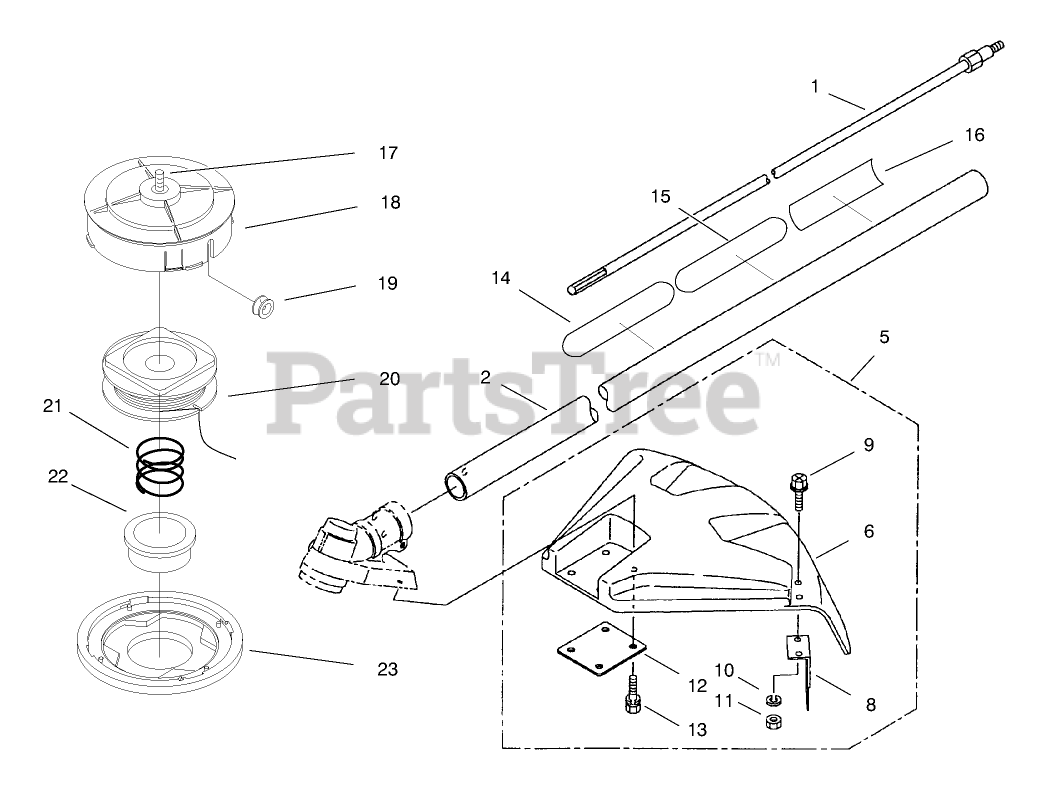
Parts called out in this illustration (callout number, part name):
1	ASM - DRIVESHAFT
2	ASSEMBLY-DRIVESHAFT TUBE
6	COVER - SAFETY
8	CUTTER - STRING
11	NUT M5
14	DECAL - CAUTION
15	DECAL - CAUTION
16	DECAL - TORO
18	HOUSING
19	EYELET
20	SPOOL W/LINE (LH)
21	SPRING
22	BUTTON
23	COVER (SN-348L)
